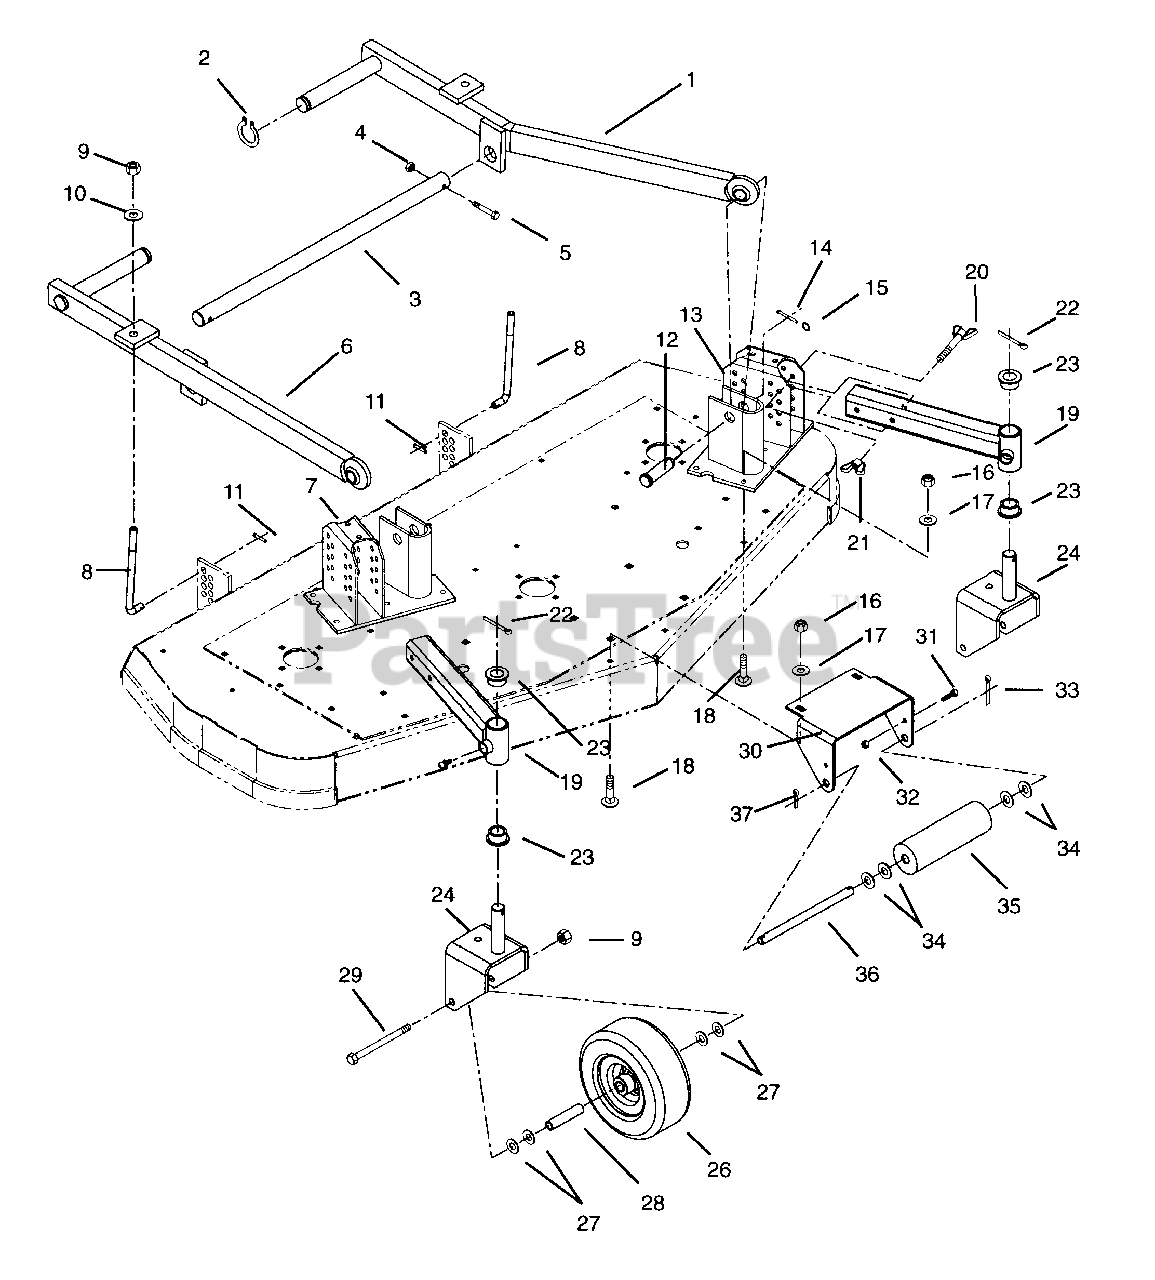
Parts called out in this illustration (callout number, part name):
1	Weldment, Lift Arm Left Hand
2	Ring-Retaining-External 1.150 x .093
3	Shaft, Mower Lift
4	Nut-Locking-Jam-Center .375-16
5	Bolt-Hex .25-20 x 1.75 Grade 2
6	Weldment, Lift Arm Right Hand
7	Weldment, Lift Arm Mount Right Hand
8	Rod, Rear Height Adjustment
9	Nut-Locking-Nylon .50-13 Grade 5
10	Washer-Flat-Steel .531 x 1.250 x 1.00
11	Pin-Klik 1.000 x .188 x 1.25
12	Pin-Clevis .875 x 3.00
13	Weldment, Lift Arm Mount Left Hand
14	Pin-Clevis .313 x 2.62 Grade 5
15	Ring-Retaining-External 2.240 x .180
16	Nut-Locking-Nylon .375-16 Grade 2
17	Washer-Flat-Steel .406 x .812 x .065
18	Bolt-Round Head Square Neck .38-16 x 1.0
19	Caster Wheel Mount
20	Bolt, Wing 3/8-16 x 3
21	Nut, Wing 3/8-16
22	Pin-Cotter .188 x 1.625
23	Bushing-Flange 1.020 x 1.385 x .75 x 1.75
24	Weldment, Caster Fork
25	Fitting-Lube .25-28 x .256
26	Wheel 9 x 3.50
27	Washer-Flat-Steel.500 x 1.250 x.083
28	Spacer .532 x .748 x 3.34
29	Bolt-Hex .50-13 x 5.50
30	Bracket, Roller Right Hand
31	Bolt-Hex .25-20 x .75 Grade 5
32	Nut-Locking-Nylon .250-20 Grade 2
33	Pin-Cotter .250 x 2.00
34	Washer-Flat-Steel .656 x 1.312 x .095
35	Roller, Gage
36	Shaft, Center Roller
37	Pin-Cotter .25 x 1.00
